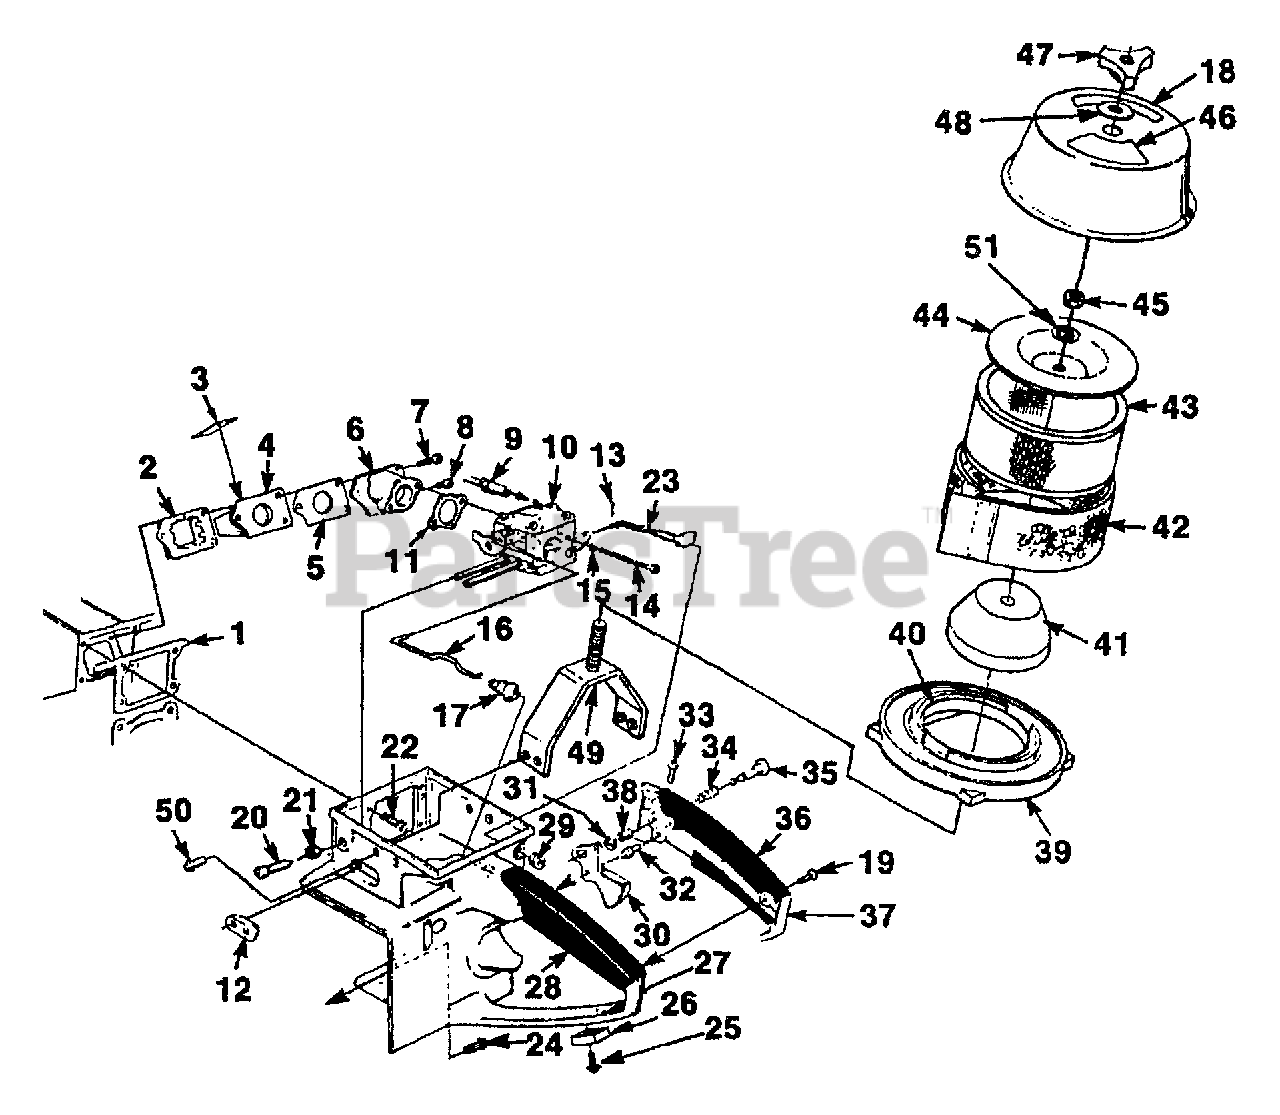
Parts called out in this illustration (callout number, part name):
2	RETAINER-Reed
3	REED-Valve
4	SEAT-Reed Valve
6	SPACER-Carburetor
7	SCREW-(8-32 X 1 1/4")
8	SCREW-Thread form. (8-32 X 1 1/4")
9	FUEL LINE
10	CARBURETOR
12	GROMMET
13	COTTER PIN
14	SCREW-(10-32 X 1 7/8")
15	WASHER-Lock
16	ROD-Throttle
17	BOOT-Throttle Rod
18	DECAL-Instruction
19	SCREW-Pan hd, (8-32 X 1/2")
20	SCREW-Idle Adjustment
21	NUT-Jam (5/16-24)
22	SCREW-Hex hd. (12-24 X 5/8")
23	CHOKE ROD
24	SCREW-Hex hd. (12-24 X 7/8")
25	SCREW-(10-24 X 1/2")
26	PAD-Wear
27	HANDLE-Throttle
28	GRIP-Throttle Handle
29	GROMMET
30	TRIGGER
31	RING-Retaining
33	SCREW-(8-32 X 5/8")
34	SPRING-Throttle lock
35	PIN-Throttle
36	GRIP-Throttle Handle
37	COVER-Throttle Handle
38	BUSHING
39	RING & GASKET ASSY.
41	FILTER-Air
42	PRE FILTER-Felt
43	ELEMENT-Air Filter
44	COVER-Filter Element
45	NUT-Hex (5/16-18)
46	DECAL-Warning
47	KNOB-Handle
48	GASKET
49	BRACKET-Cover
